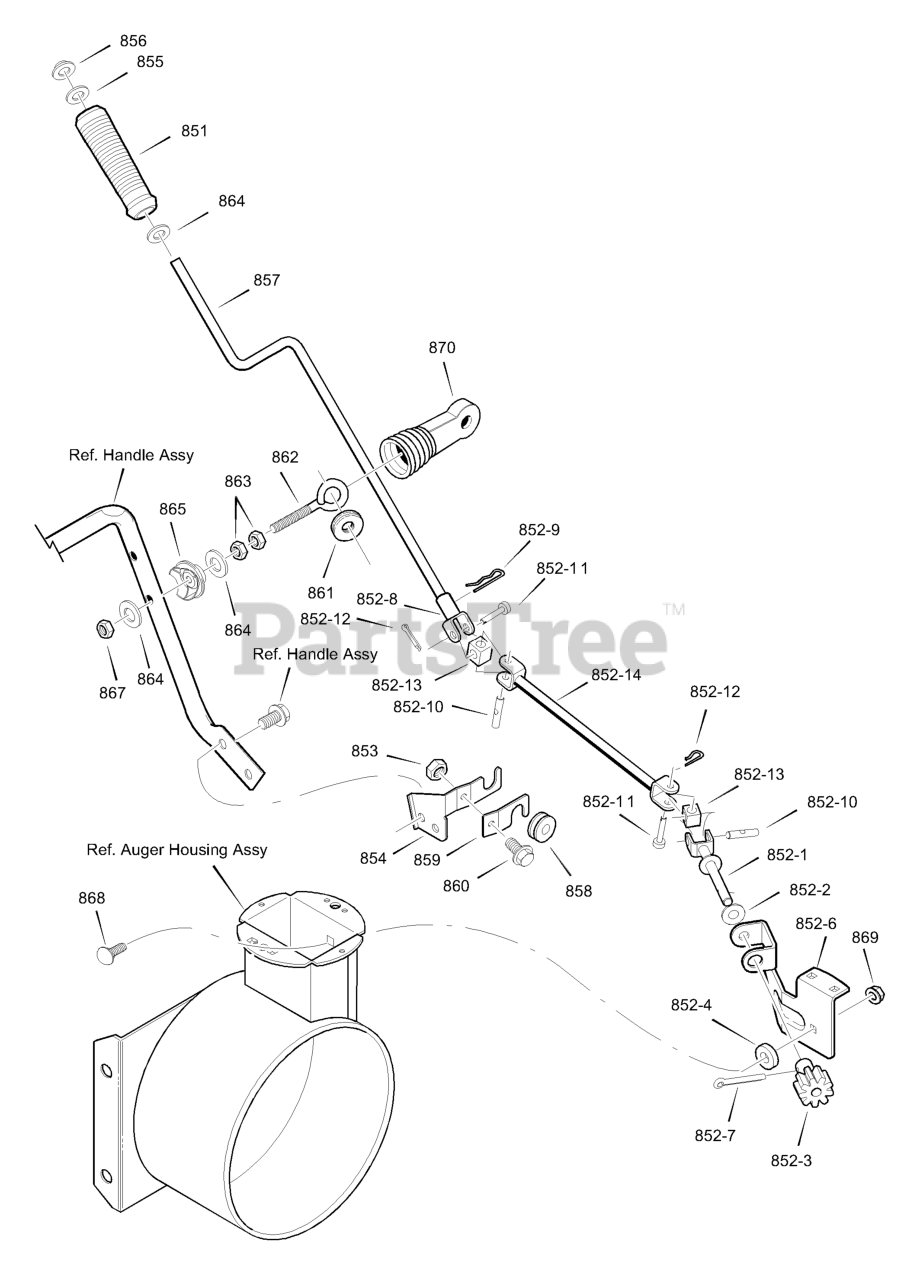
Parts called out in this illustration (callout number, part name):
851	GRIP, CHUTE CRANK ROD
852-1	ASSEMBLY, YOKE & ROD
852-2	WASHER, CURVED SPRING
852-3	GEAR, CHUTE ROTATION 9T
852-6	BRACKET, GEAR MOUNT
852-7	PIN, COTTER
852-8	ASSEMBLY, YOKE ADAPTER YZ
852-9	PIN, HAIR
852-10	PIN, UNIVERSAL JOINT
852-11	PIN, CLEVIS
852-12	PIN, HAIR
852-13	HOUSING, UNIVERSAL
852-14	CRANK, LOWER CHUTE
853	NUT 1/4-20 x 1/2
854	BRACKET, SUPPORT CHUTE
855	FLATWASHER
856	NUT, PUSH ON 3/8"
857	CRANK, ASSY CHUTE
858	GROMMET
859	BRACKET, MATING CHUTE
860	BOLT 1/4-20 X 1/2
861	GROMMET, EYE BOLT
862	EYE BOLT 3/8-16X6.00
863	NUT, 3/8-16 HEXJAM
864	FLATWASHER .406X.81X.066
865	ADAPTER, BOOT
867	NUT, 3/8-16 HEXNYL
868	BOLT, CARRIAGE 1/4-20 X 1.00
870	BOOT, EYE BOLT
